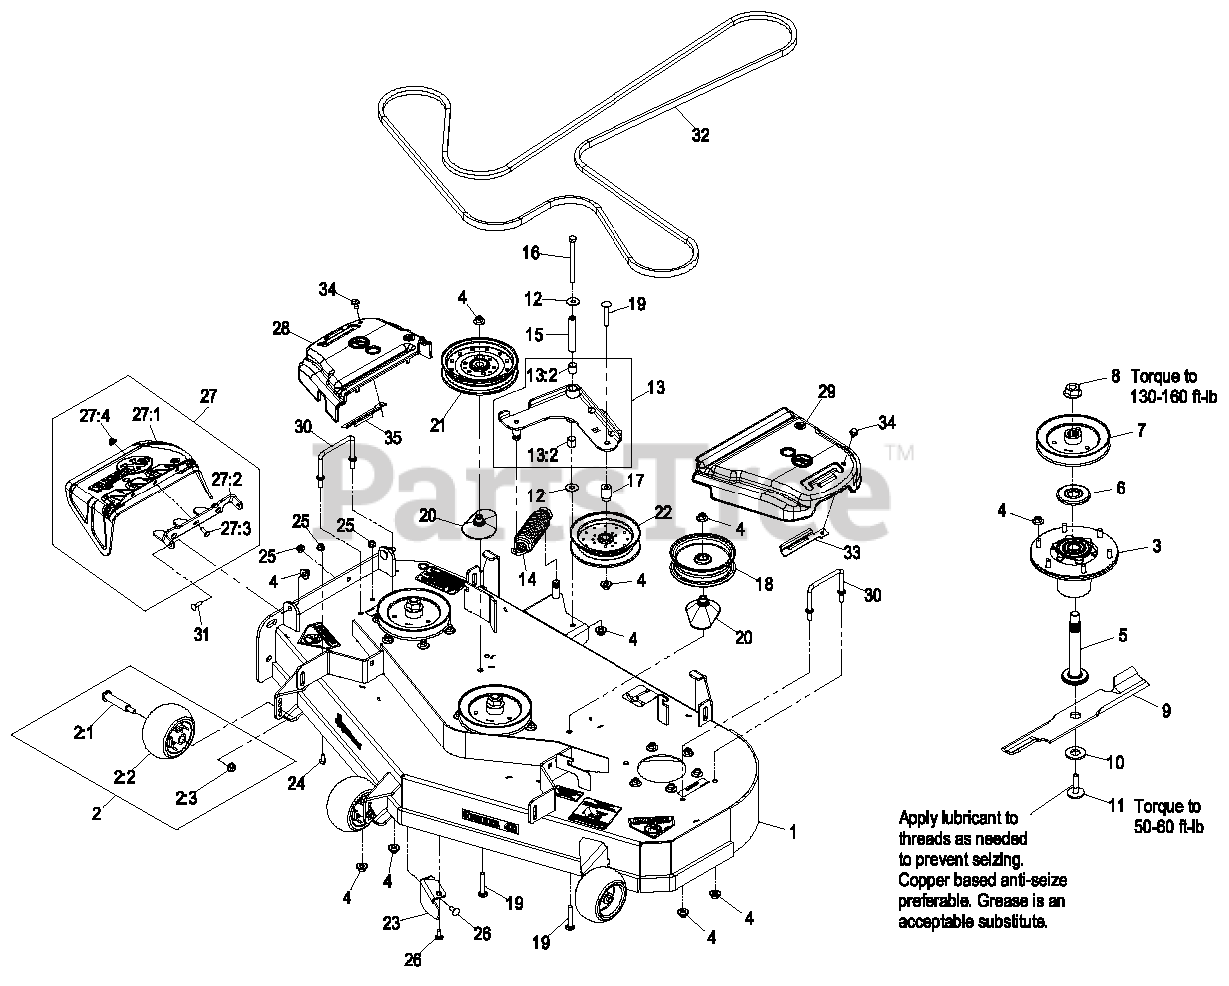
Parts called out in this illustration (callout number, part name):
1	ASM, 48 DECK W/ DECALS
2	ANTI-SCALP ROLLER KIT
2:1	BOLT-SHOULDER
2:2	ROLLER-SCALP, ANTI
2:3	NUT-HF, NI
3	ASM,CUTTER HOUSING W/BEAR
4	Nut-Nyloc 3/8-16 Flg
5	SPINDLE,HEX PILOT 5.5" DE
6	GUARD,BEARING TOP .989
7	SHEAVE,BLADE DRIVE 5.90
8	NUT-FLANGE
10	WASHER-BLADE DRIVE
11	BOLT-BLADE, SEM
13:2	SLEEVE-BEARING
15	BUSHING-TIGHTENER, PIVOT
16	SCREW-HH
17	BUSHING,IDLER
19	BOLT-CARR, SHORT NECK
20	SPACER-PULLEY
23	BAFFLE,DISCHARGE 483
24	SCREW-HH
25	NUT-HF, NI
26	SCREW-CARR
27	ASM,DISCHARGE CHUTE
27:1	CHUTE,DISCHARGE
27:2	BRACKET,DISCHARGE CHUTE
27:3	SCREW-CARR
27:4	Nut-Nyloc 3/8-16 Flg
28	COVER-BELT, RH
29	COVER-BELT, LH
30	WIREFORM-COVER
31	BOLT-CARR
32	BELT-B154.88
33	RETAINER,COVER LH
35	RETAINER,COVER RH
